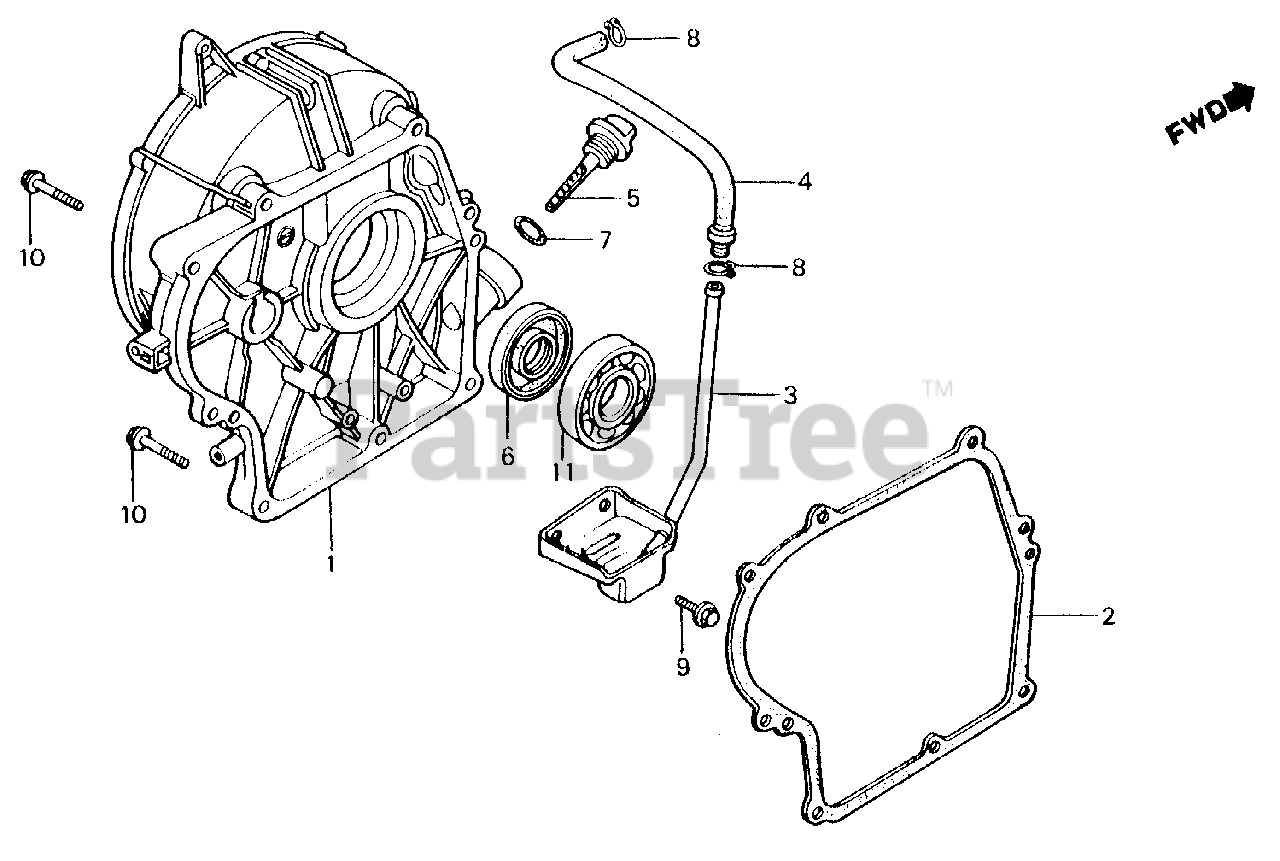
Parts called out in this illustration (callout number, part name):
1	COVER, CRANKCASE
2	GASKET, CASE COVER
4	TUBE, OIL ALERT
5	CAP, OIL FILLER
6	OIL SEAL (30X46X8)
7	O-RING (26X2.7)
8	CLIP, TUBE (C11)
9	BOLT, FLANGE (6X16)
10	BOLT, FLANGE (8X40)
11	BEARING, RADIAL BALL (6206)
